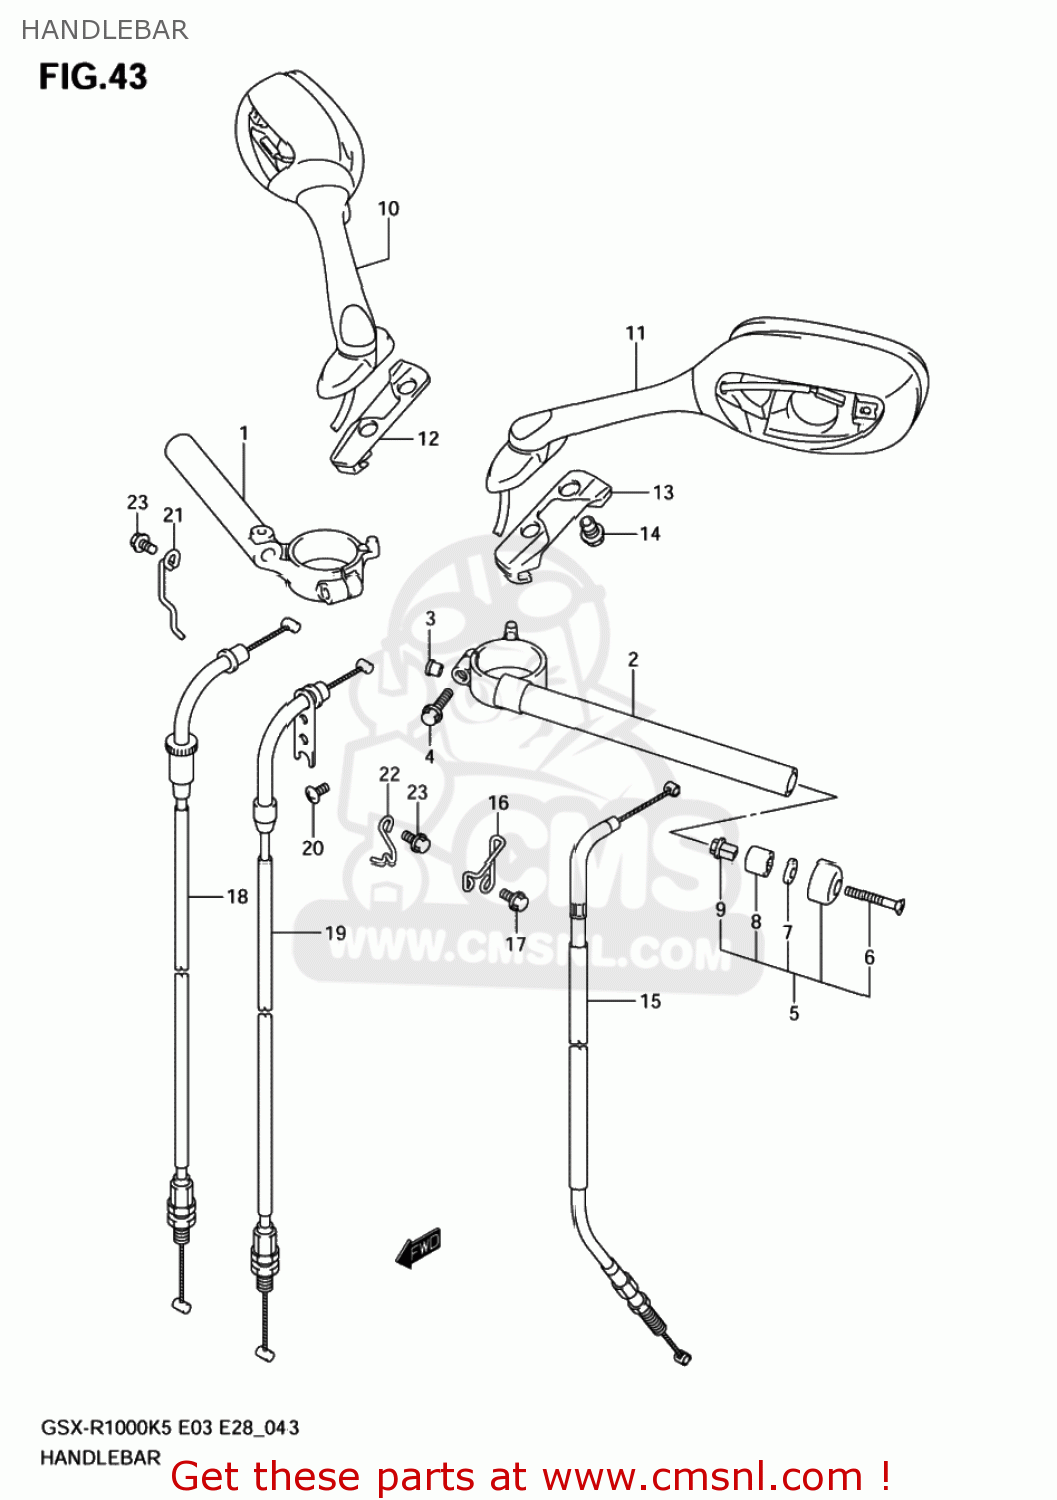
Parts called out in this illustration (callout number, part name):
1	HANDLEBAR,R
2	HANDLEBAR,L
3	CAP,HANDLEBAR
4	BOLT,HANDLEBAR
5	BALANCER SET,H
6	SCREW
7	WASHER(6.5X16X4)
8	EXPANDER,HANDLE BALANCER
9	NUT,HANDLE BAL
10	MIRROR ASSY,RE
11	MIRROR ASSY,RE
12	CUSHION,RR MIRRORR,R
13	CUSHION,RR VIEW MIRRORR
14	NUT,REAR VIEW
15	CABLE ASSY,CLUTCH
16	GUIDE,CLUTCH CABLE NO.1
17	BOLT
18	CABLE ASSY,THROTTLE NO.1
19	CABLE ASSY,THROTTLE NO.2
20	SCREW
21	GUIDE,THROTTLE CABLE
22	GUIDE,CABLE
23	BOLT
